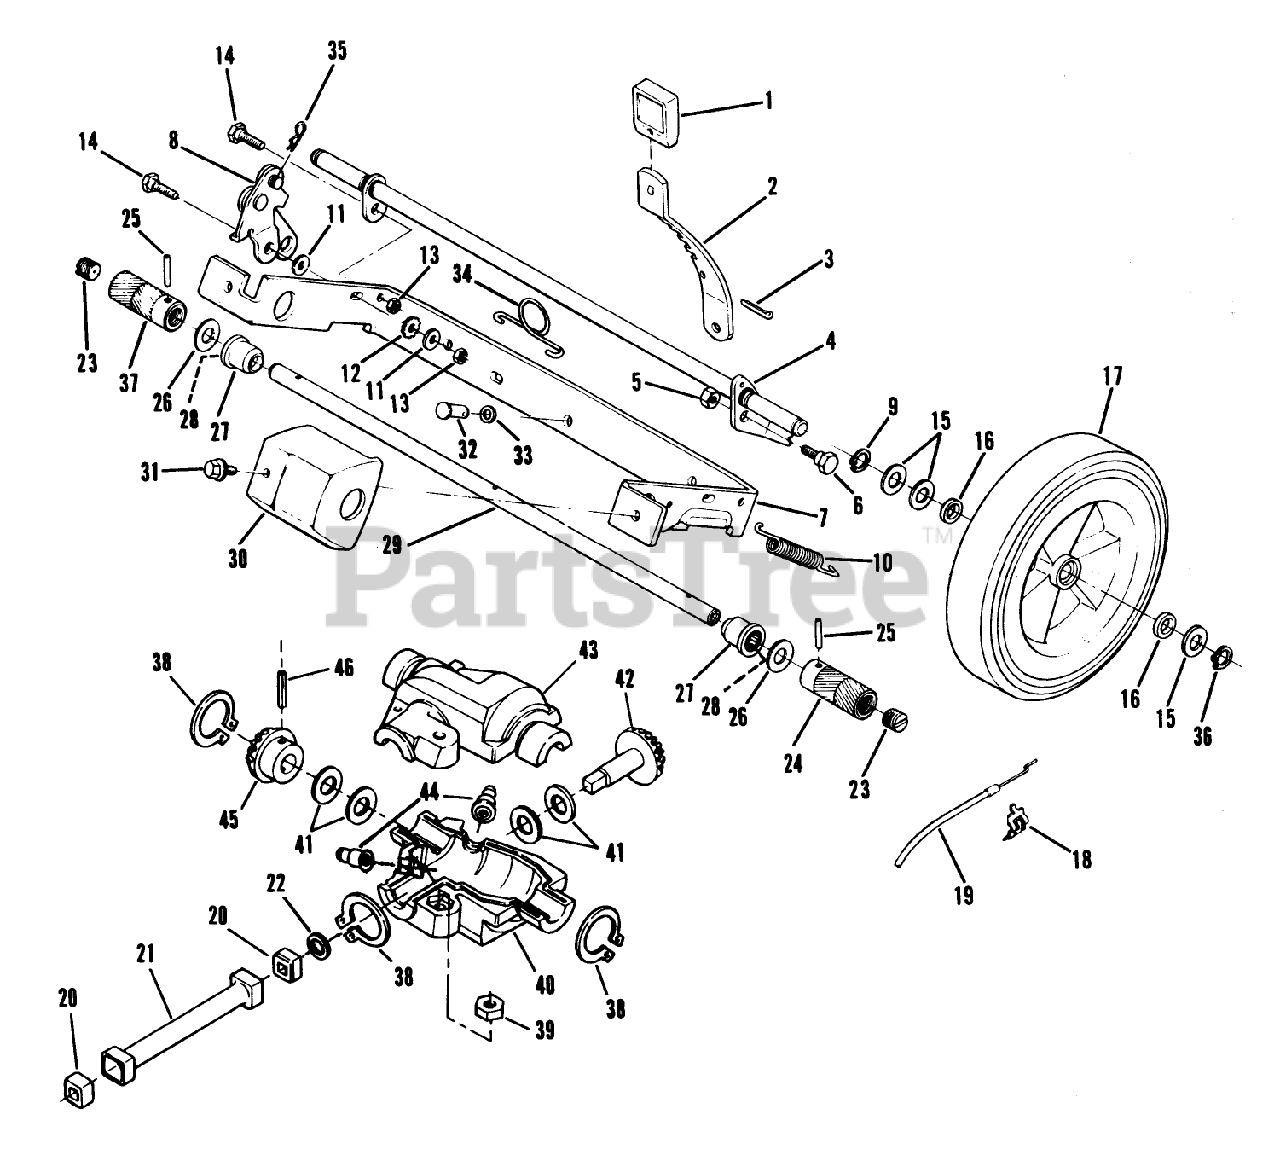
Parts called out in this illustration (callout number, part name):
1	Knob-Rear Ht. Adj. Lever
1	Knob-Rear Ht. Adj Lever
2	Lever-Rear Height Adjust
3	Cotter Pin
5	LOCKNUT E
6	BOLT RB&W
7	BRK-21" AXLE
9	RET RING
11	WASHER S
13	STOP NUT
14	BOLT RB&W
20	BUSHING
23	GREASE PLUG
24	ROLLER-LH
28	BEARING AY F
29	DRIVE SHFT TAG AY
33	WASHER SPRING LAR
34	SPRING N.A.S
36	RET RING
37	ROLLER-RH
39	LOCKNUT E
41	THRUST WASHER
44	ZERK FITTING
46	ROLL PIN
